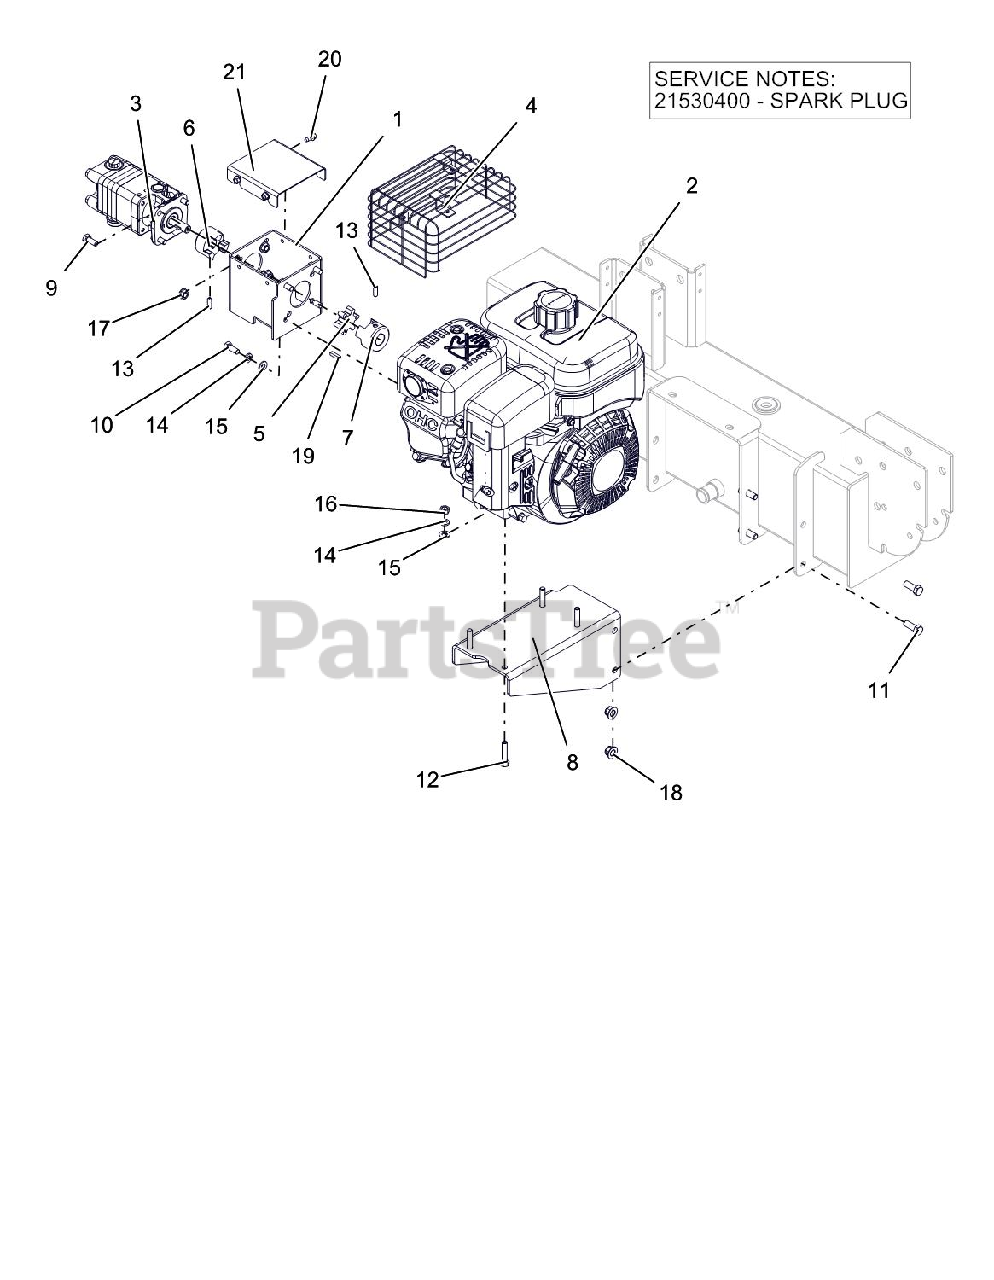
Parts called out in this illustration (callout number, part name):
1	WLDMT, PUMP MOUNT BRKT
2	PLUG, SPARK - TEC. SNO-THRO
2	ENGINE,SUBARU 6HP SP170 (CARB)
3	PUMP,SPLITTER-11 GPM
4	GUARD,MUFFLER,SUB 20A-37303-11
5	SPIDER - URETHANE
6	COUPLER - DRIVE 1/2"
7	COUPLER - DRIVE, 3/4"
8	MOUNT-ENGINE
9	@BLT-HEX .31-18X.75 GR5 YWZC
10	BLT-HEX .31-24X.75 YWZC GR5
11	@BLT-HEX .38-16X1.00 GR5 YWZC
12	@BLT-HEX .31-18X1.50 GR5 YWZC
13	SCR,SET .25-20X.75 PCPT SH
14	WSHR-LK .312X.097 HVY YWZC
15	@WSHR-FL-STL.344X.688X.065YWZC
16	@NUT-HEX .31-18 YWZC
17	@NUT-LK-TOP-FLG .31-18 YWZC
18	@NUT-LK-NYL-FLG .38-16 YWZC
19	KEY-SQ .188X.75X.188
20	SCR-TAP .25-20X.50 HWH TR YWZ
21	COVER W/DECALS
